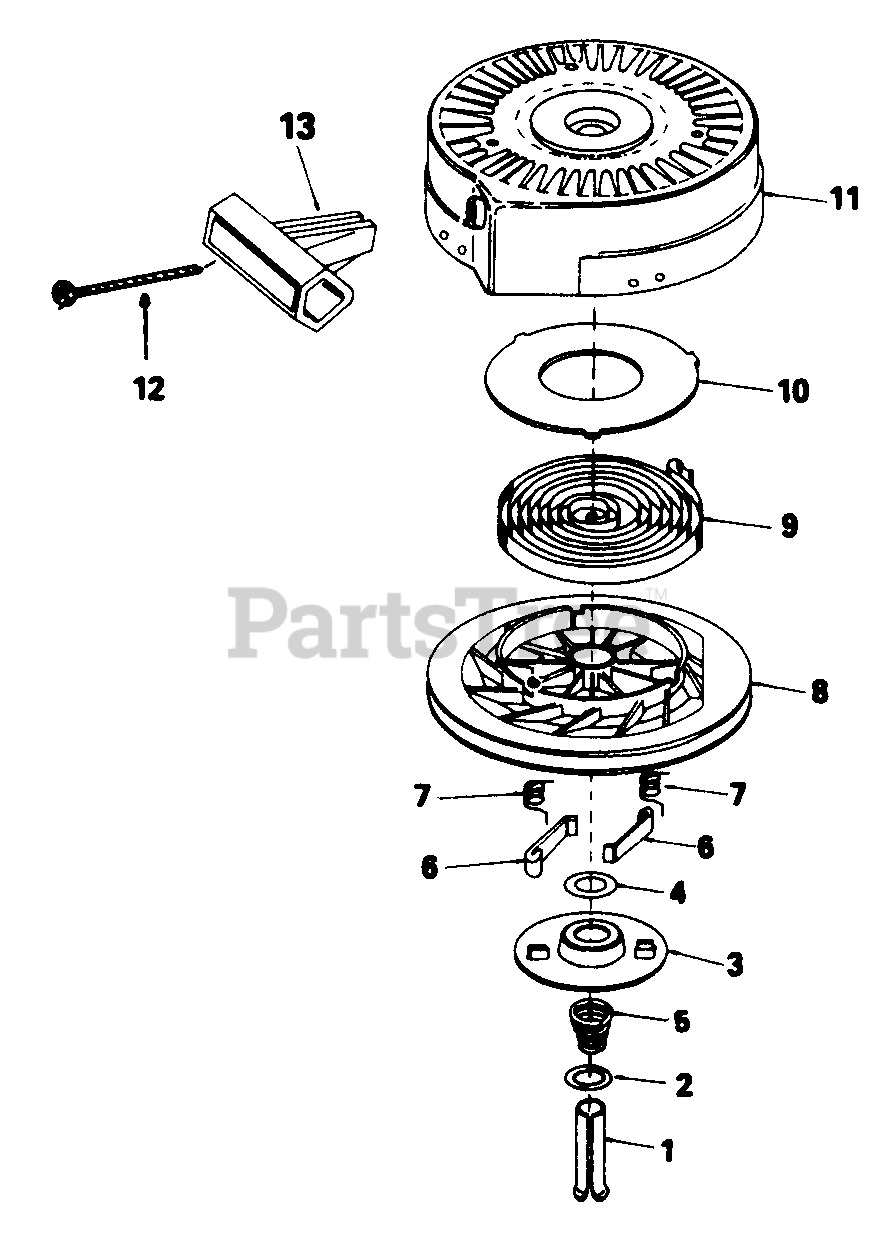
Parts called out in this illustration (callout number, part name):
1	Pin, Spring
5	Spring, Brake
6	Dog, Starter
7	Spring, Dog
9	Spring, Rewind
10	Cover, Spring
11	Housing Ass'y., Starter
12	Rope, Starter (Length 98" & 9/64" Dia.)
13	Handle, Starter
